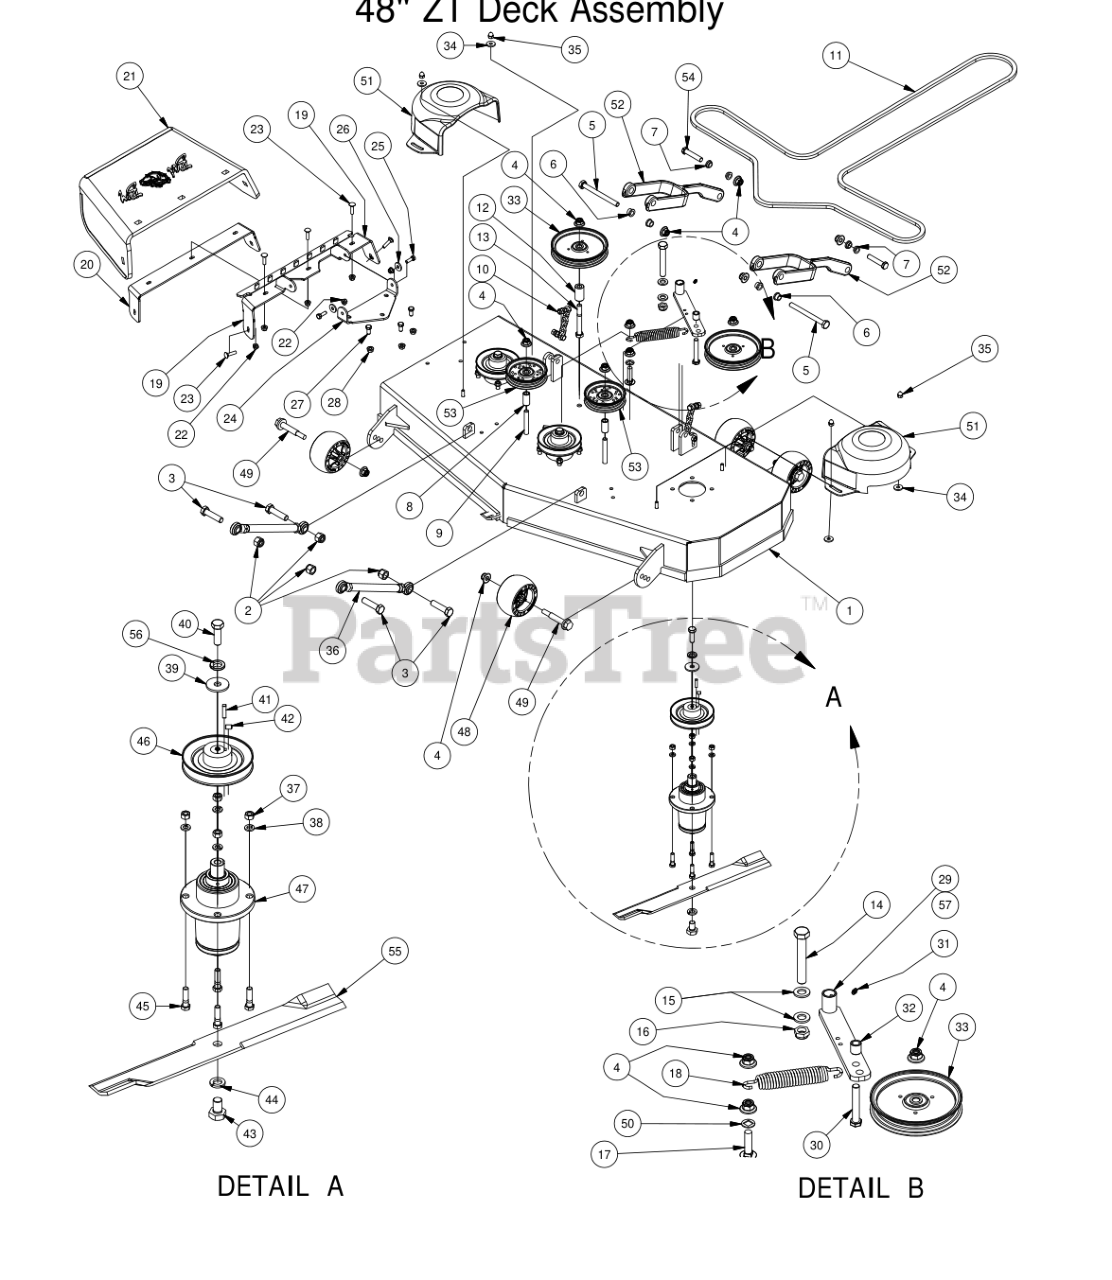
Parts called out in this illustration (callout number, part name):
1	ZT/Maverick 48" Deck
2	5/8 Std NC Nylock Nut
3	5/8" x 2 1/2" Grade 5 Hex Bolt (Coarse)
4	1/2-13 Nylon Flange Nut
5	1/2" x 5 1/2" Bolt
6	Flange Bushing For Upper Deck Arm
7	Flange Bushing For Lower Deck Arm
8	.502 ID X.750 OD X 1.500 Long Spacer
9	1/2 x 3 1/2 Flange Bolt Grade 8
10	Chain assembly
11	48 Deck Belt
12	1 3/4" Pulley Spacer
13	1/2" x 4" Bolt (Grade 8)
14	5/8" x 4" Hex Bolt
15	.630 ID Plastic Washer
16	5/8-11 Nylon Insert Jam Half Nut
17	1/2 x 2" Carriage Bolt
18	2009 Deck/Pump Idler Spring
19	Discharge Upper Chute Bracket
20	Discharge Lower Chute Bracket
21	Rubber Discharge Chute
22	5/16" Nylon Flange Nut
23	5/16" x 1 1/4" Carriage Bolt
24	Discharge Chute Hanger (Deck Mounted)
25	5/16" x 1" Bolt
26	.360 ID Plastic Washer
27	3/8" x 3/4" Hex Bolt
28	3/8" Flange Nut
29	Deck Idler
30	1/2-13 x GR 5 Hex Bolt Zinc
31	1/4" Press in Grease Fitting
32	Spacer 3/4 OD x 1/2 ID x 3\4 Length
33	5-3/4 Idler Pulley
34	.360 ID Plastic Washer-Black
35	Acorn nut-pulley Cover
36	Turnbuckle (Top Link)
37	3/8" Hex Nut
38	3/8" Lock Washer
39	1/2 Belleville Washer
40	1/2"-20 x 1 1/2 - Grade 5 Fine Thread Bolt
41	1/4" x 1" Key
42	5/16 Set Screw
43	5/8" x 1 1/2" Grade 8 Hex Bolt (Fine)
44	5/8" Lock Washer
45	3/8" x 1 1/4" Hex Bolt
46	5" Spindle Deck Pulley
47	Spindle Assembly
48	Anti-Scalp Rollers
49	Deck Wheel Bolt
50	.517 Square Hole Round Washer
51	Pulley Cover
52	Deck Arm Assembly
53	4-3/4 Idler Pulley
54	1/2" x 3" Hex Bolt
55	Fusion Blade
56	1/2" Lock Washer Zinc
57	Idler Arm Assembly (Parts 4,30,31,32,33,34)
